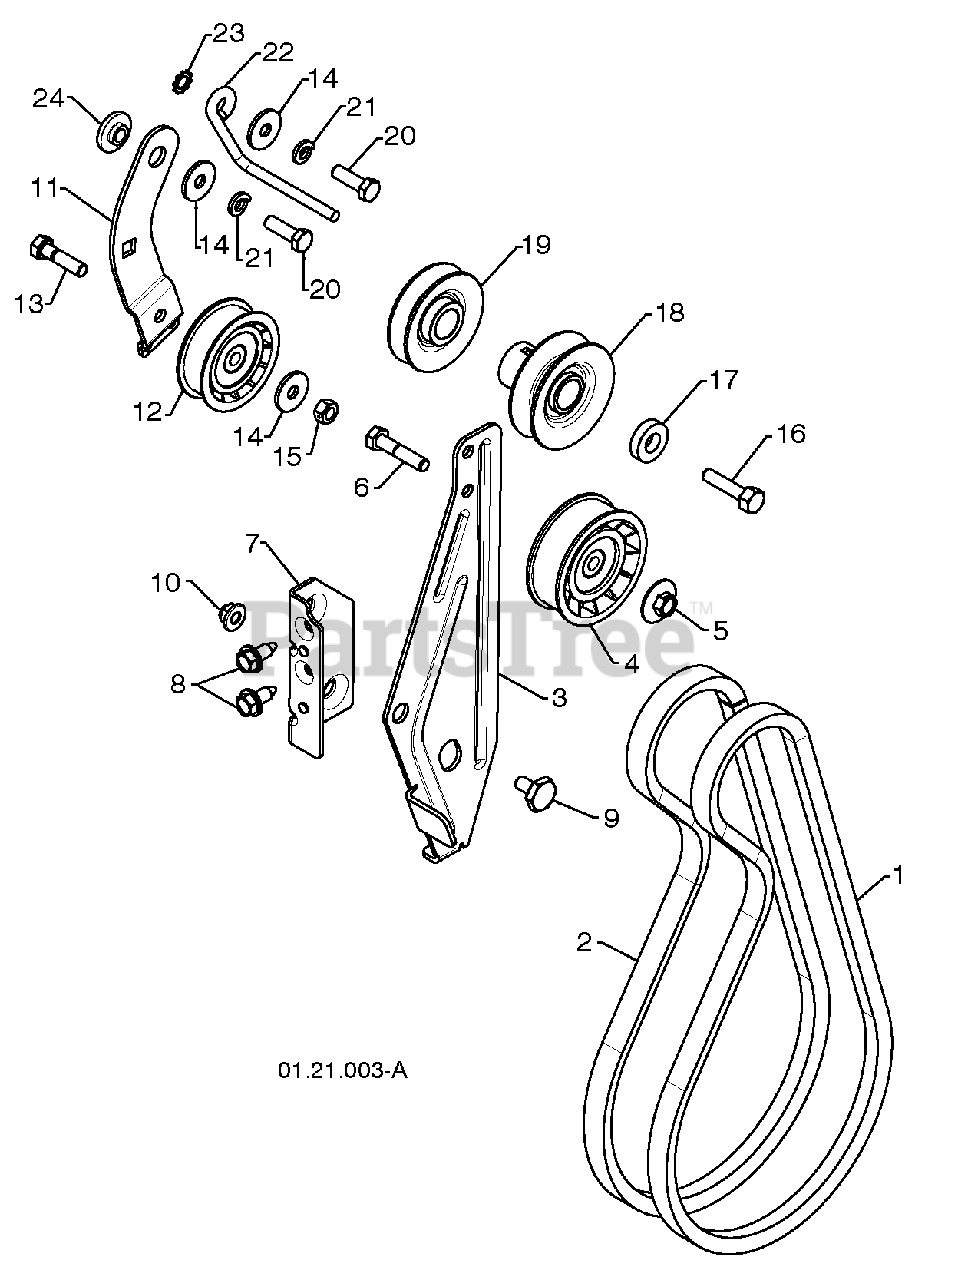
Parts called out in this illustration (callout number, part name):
1	IMPELLER BELT
2	TRACTION BELT
3	IDLER ARM BRACKET
4	IDLER PULLEY
5	NUT 5/16-18
6	SCREW 5/16-18 X 1 .50
7	IDLER BRACKET
8	SCREW 5/16-18 X .625
9	SHOULDER BOLT 5/16-18 X .500
10	NUT 5/16-18 NYLOCK
11	TRACTION IDLER ARM
12	TRACTION PULLEY
13	SCREW 5/16-18 X 1 .00
14	WASHER
15	NUT 5/16-18
16	SCREW 3/8-24 X 1.375
17	WASHER
18	PULLEY ENG IMPELLER
19	PULLEY ENG TRACTION
20	SCREW 5/16-18 X 1 .00
21	LOCKWASHER 5/16
22	BELT GUIDE
23	LOCKWASHER 5/16
24	IDLER BUSHING
